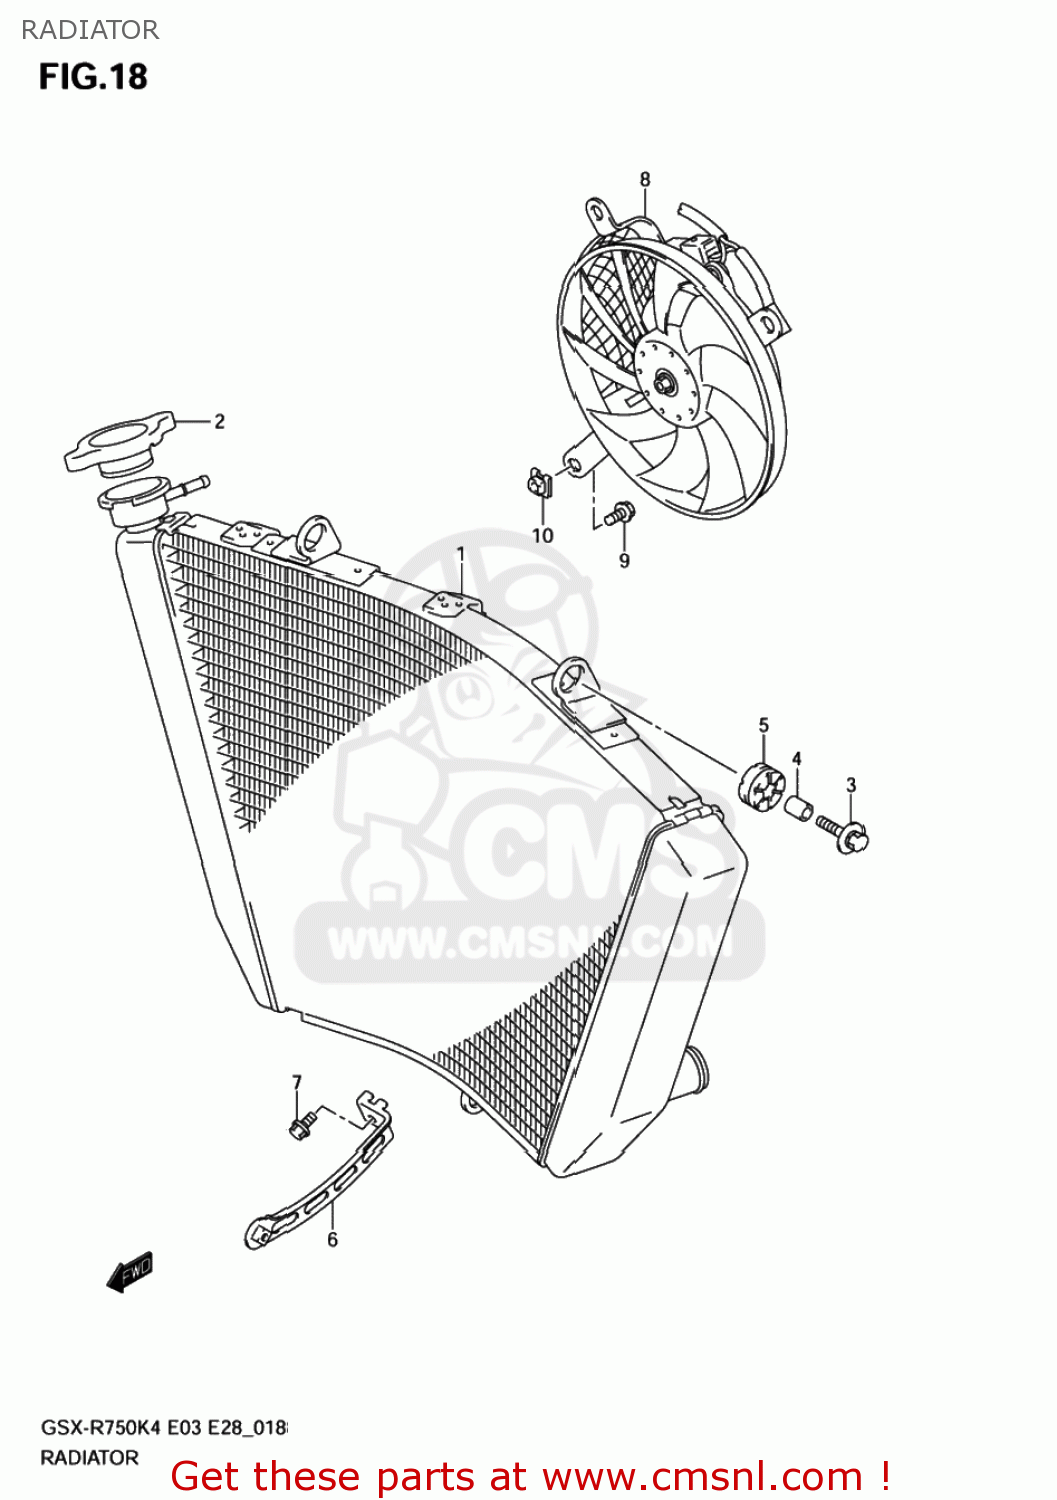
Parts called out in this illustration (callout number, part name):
1	RADIATOR ASSY,WATER
2	CAP,RADIATOR(1.1)
3	BOLT(6X25)
4	SPACER(6.5X10X12)
5	CUSHION
6	BRACKET,RADIATOR
7	BOLT
8	FAN ASSY,RADIATOR
9	BOLT,FAN ASSY
10	NUT,RADIATOR FAN
